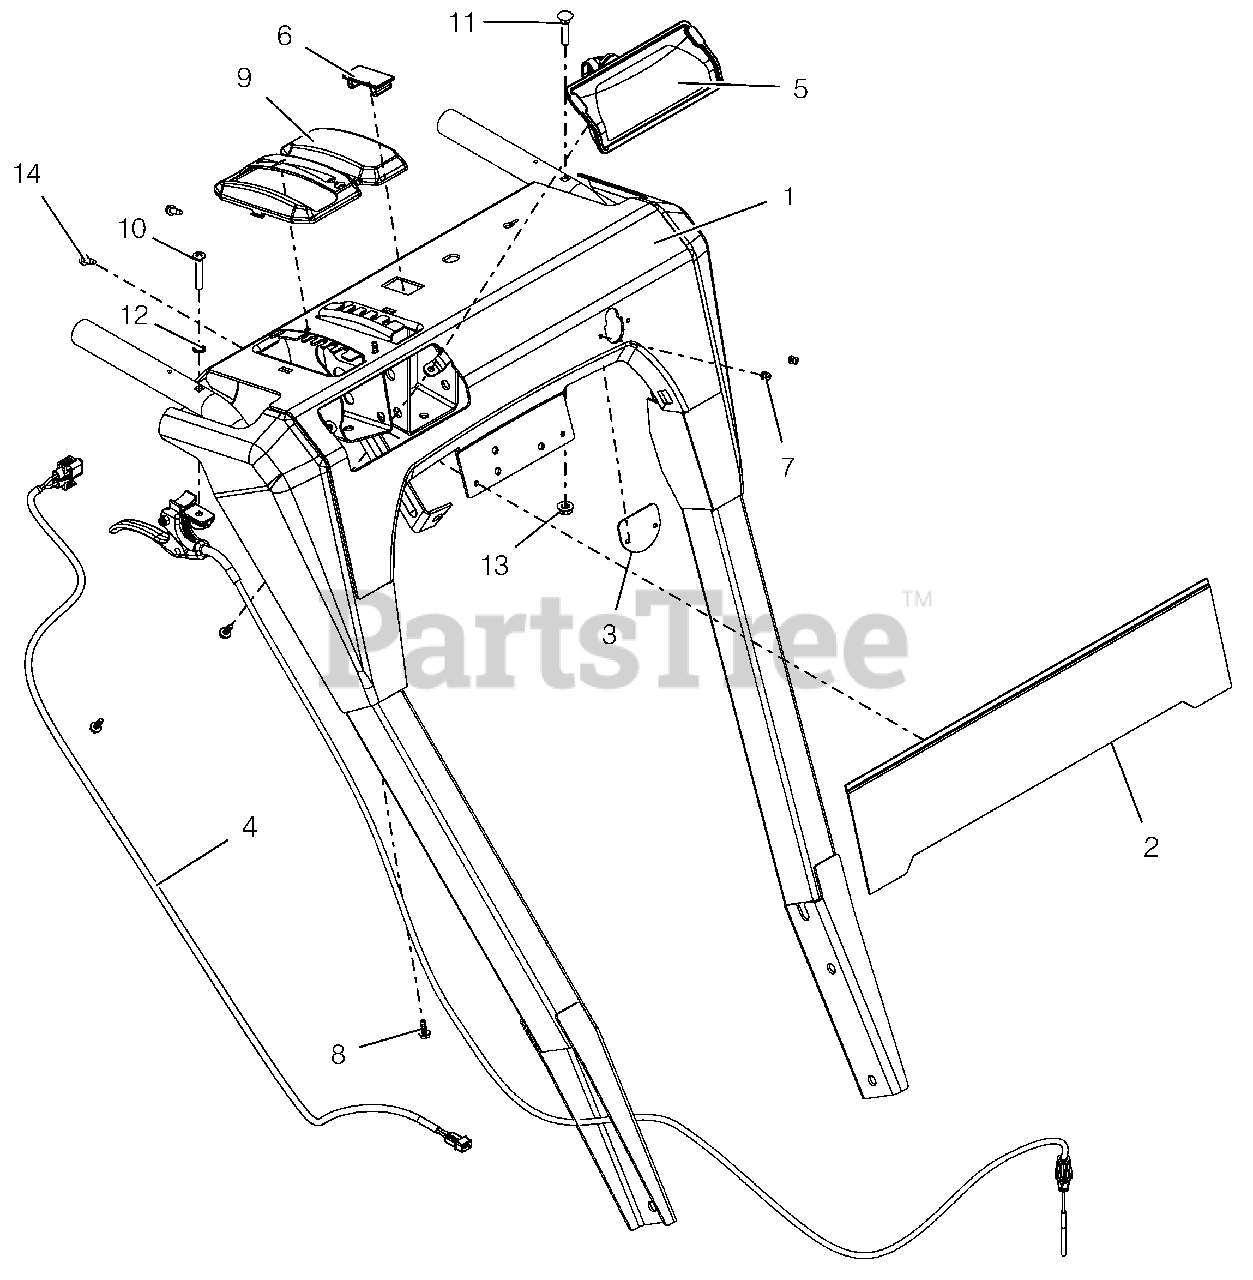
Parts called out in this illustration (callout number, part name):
1	PANEL, DASH - W/CTR DECAL
2	WLDMT, BRAND PLATE
3	COVER, DASH BRKT, BRUSH
4	HARNESS, LIGHT - DELUXE
5	HEADLIGHT ASY, HOLO 15W 2 SHOT
6	PLUG,DASH PANEL
7	RVT-POP #43 .125X.313 STL ZINC
8	SCR-TAP #10X.50 BOSS INDHXHD
9	BEZEL, SHIFT - FRICTION BRUSH
10	SCR-MCH .25-20X1.50 OVAL HD
11	BLT-RDHDXLSQNK.25-20X1.25 G5ZC
12	WSHR-LK-INT .250 TH TYA
13	NUT-LK-CTR-FLG .25-20 YWZC
14	@SCR-TAP 10-24X.50 HWH TR YWZC
